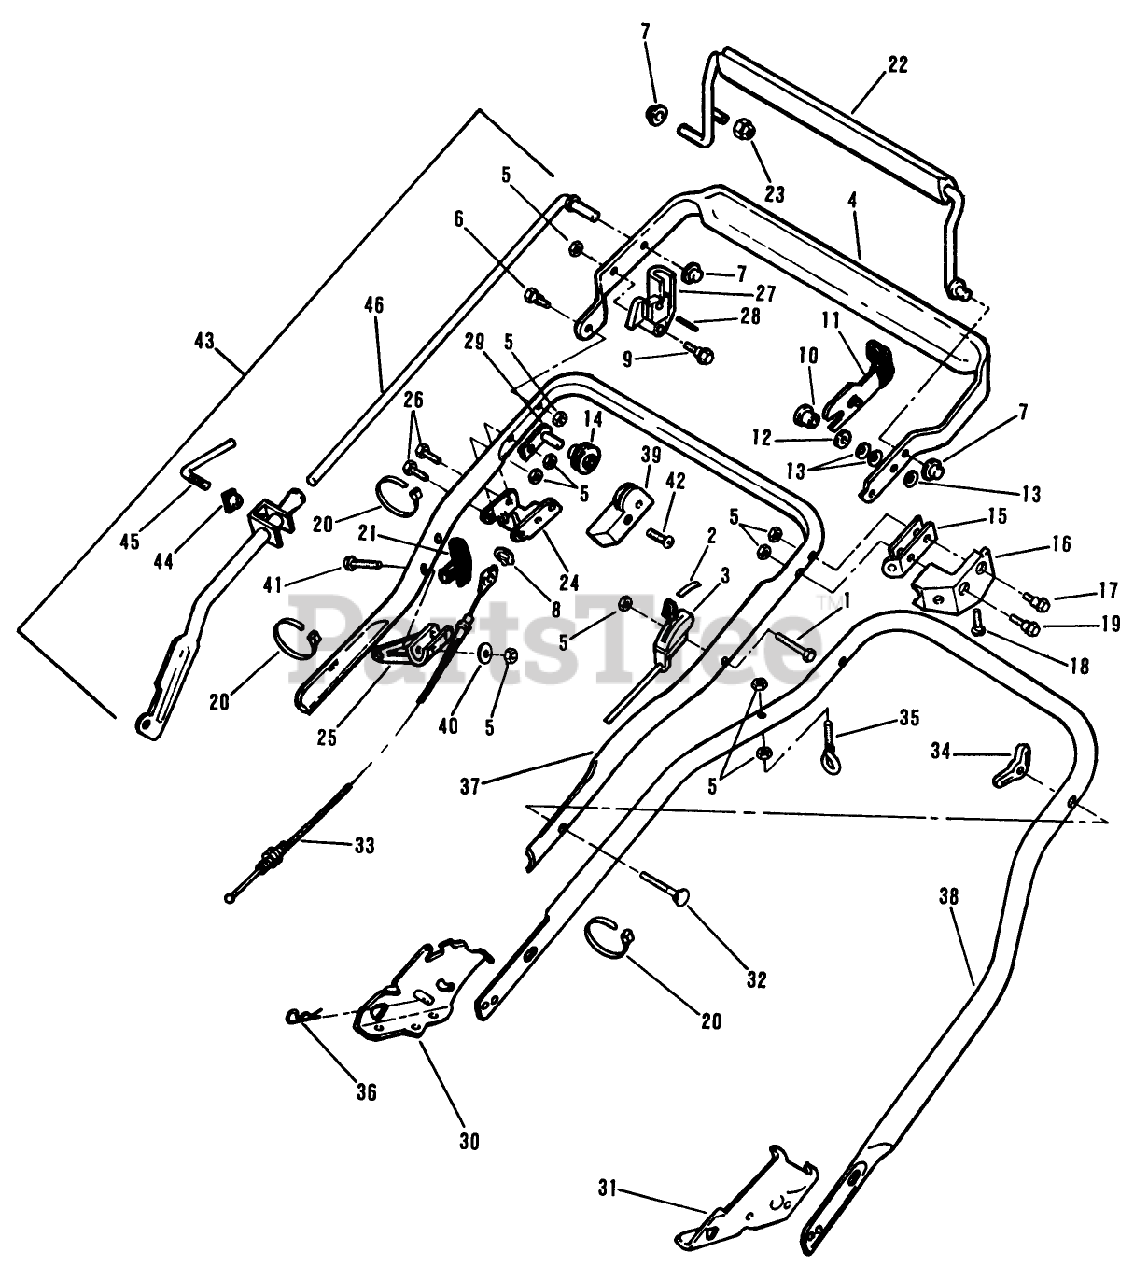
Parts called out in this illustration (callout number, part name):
3	CONTROL THROT WES
5	LOCKNUT E
6	BOLT
8	RET. RING
10	SPACER
12	WASHER M
14	PULLEY PL
15	DOWN STOP
16	LOCKOUT GUARD
17	BOLT SHOU
18	SCREW F
19	SCREW
21	HANDLE START UM&D
23	NUT ACORN
27	CAM HOFFER
30	BRACKET ASM - HANDLE, SP, RH
31	BRACKET ASM - HANDLE, SP, LH
32	BOLT QUALITY
33	CONTROL CABLE
34	NUT-WING
35	EYE BOLT WAS MFG
36	HAIR PIN
37	HANDLE SECTION
40	WASHER
43	CONTROL LEVER AY
46	CONTROL ROD
